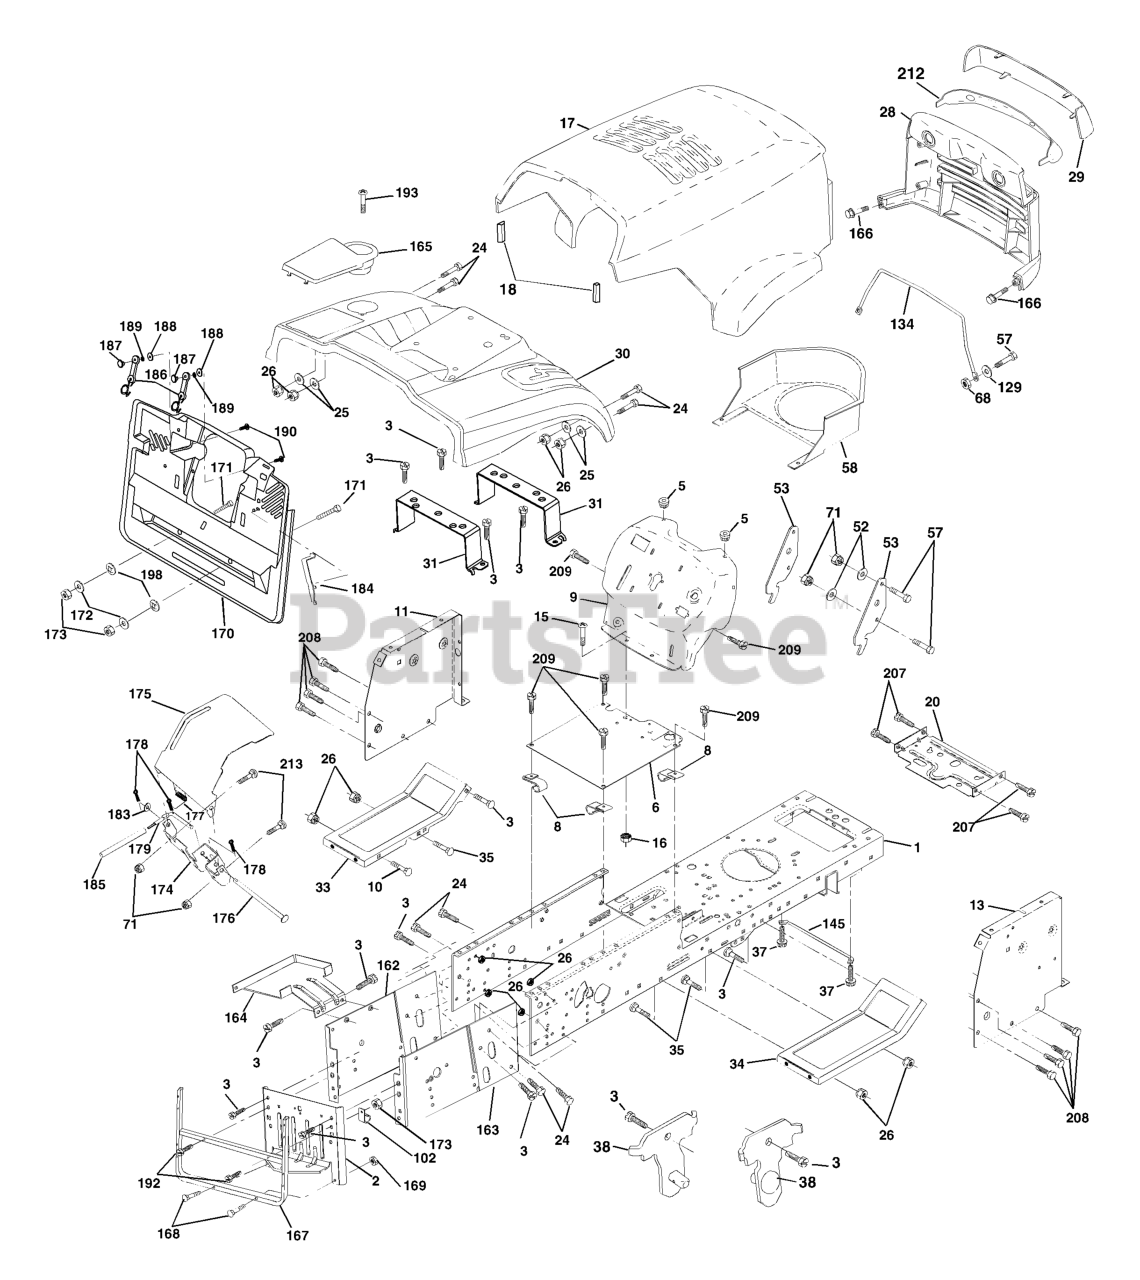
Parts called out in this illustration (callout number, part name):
1	CHASSIS STAMPING
3	SCREW 3/8-16X3/4
5	BUMPER.RUBBER.HOOD
6	SADDLE FLAT
8	CLIP,INSULATOR
10	BOLT D
11	PANEL DASH LH
13	DASH PANEL RH
15	Screw, Machine, Truss Head 5/6-18 UNC x 3/4
16	NUT
17	HOOD
18	BUMPER HOOD T
20	PLATE MTG
24	BOLT
25	WASHER
26	NUT
28	GRILL
29	LENS
31	BRACKET SUPPORT FENDER
33	FOOT REST LH
34	FOOTREST RH
35	BOLT
37	Screw Thdrol 5/16-18 x 1/2 TYT
38	BRACKET
52	WASHER
53	BRACKET PNT PICK OFF LT/PL
57	BOLT
58	AIR DUCT P/L/LT
68	NUT
71	NUT.CROWNLOCK.1/4
102	CLIP T
129	WASHER
134	ROD SUPPORT HOOD LT/PL HUS.
145	ROD PIVOT CHASSIS/HOOD
162	Bracket Exten Chassis Lh CRD
165	COVER BATTERY
166	SCREW
167	SUPPORT.ASM.BACKPLATE
168	BOLT.ROUND.HEAD.SQUARE.NECK
169	NUT T
170	BACKPLATE ASM
171	Bolt Hex 3/8-16 x 2-1/2 Gr. 5
172	WASHER
176	HINGE PIN
177	SPRING COVER LH
178	COTTER PIN
180	BOLT RB
181	LOCKNUT
183	WASHER
184	BRACKET.ACTUATOR.BAGGER.SRD
185	TUBE LEVER
186	LATCH ASSY
187	WELDNUT
189	LOCKWASHER #10
190	SCREW
192	SCREW LT
193	Screw Truss 1/4-20 x 3/4 Tap/R
207	SCREW, 5/16-18 X 1/2
208	SCREW 3/8-16X1/2
209	SCREW, 3/8-16X3/4
212	INSERT LENS REFLECTOR
